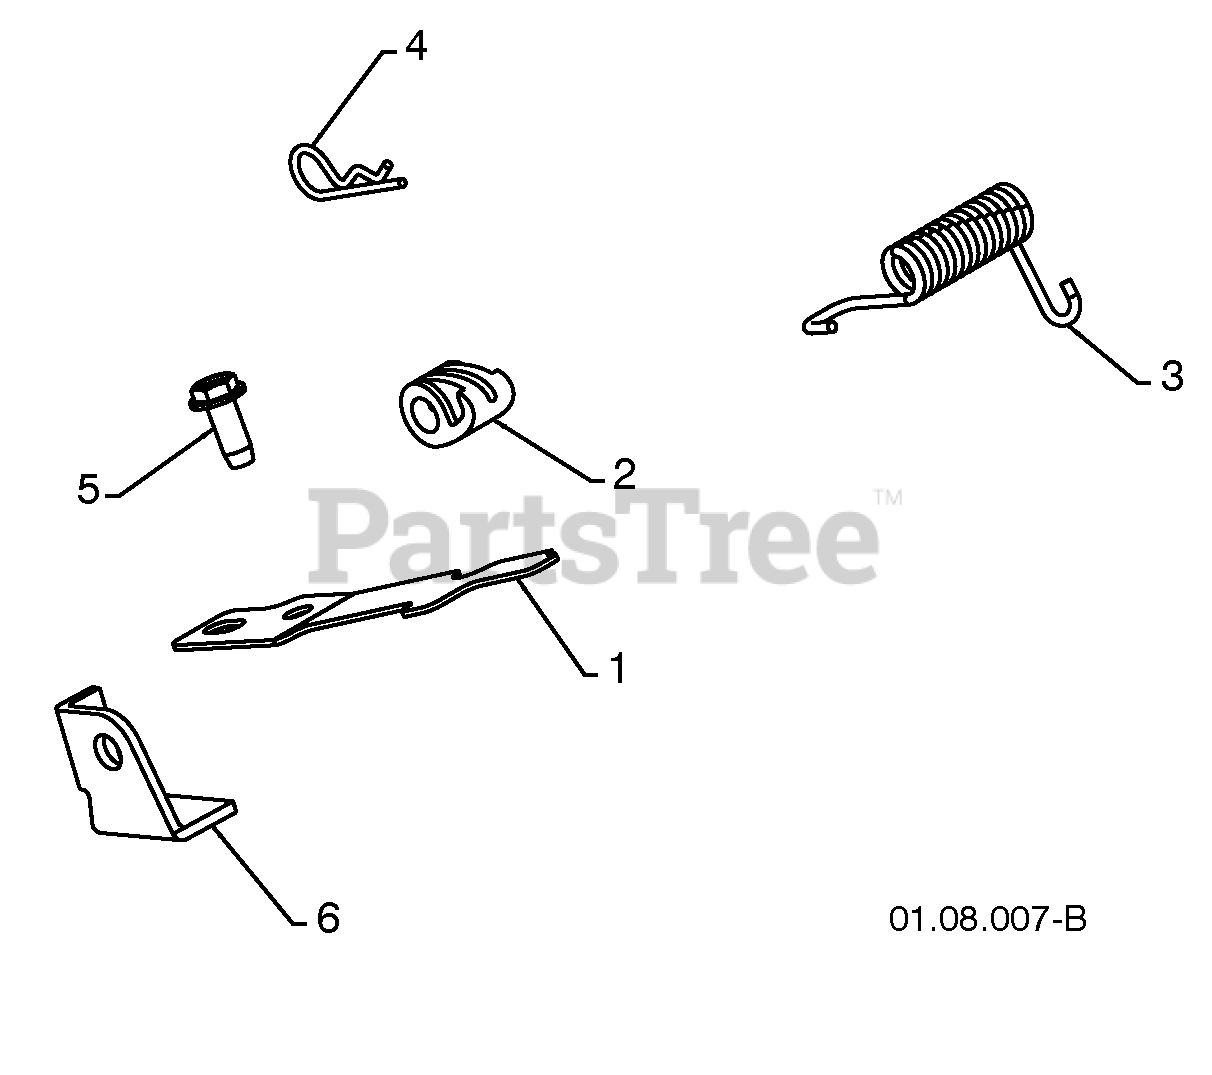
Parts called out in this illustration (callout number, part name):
1	INTERLOCK SPRING
2	INTERLOCK CAM
3	TORSION SPRING
4	RETAINER
5	SCREW 1/4-20 X .625
6	INTERLOCK STOP
